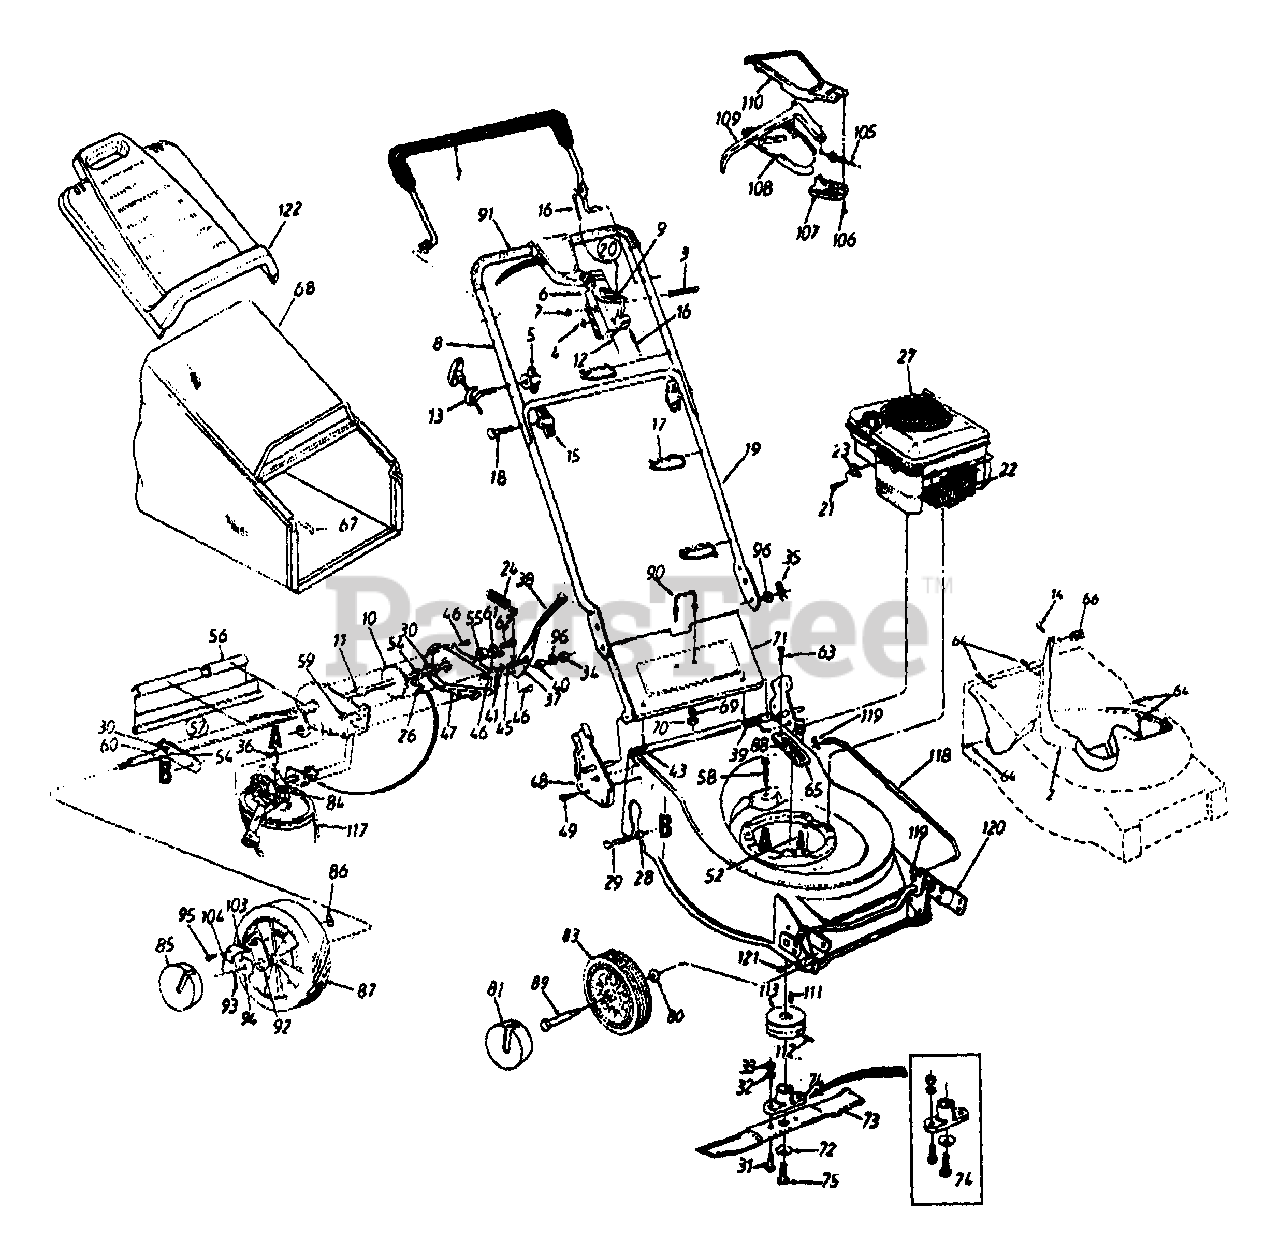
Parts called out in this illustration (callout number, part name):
1	Control Handle Ass'y
2	Rear Baffle
3	Oval C-Sunk Mach. Scr.
4	Spr. Wash. .66" I.D.
5	Wing Nut 1/4-20 Thd.
6	Throttle Body
7	Hex L-Nut 1/4-20 Thd.
9	Throttle Lever
10	Axle Ass'y. 19.12" Lg.
11	Hex Flange Brg. .506" I.D.
12	Throttle Control Wire - 60"
15	Hand Knob
16	Control Cable - 47"
17	Cable Tie
18	Curved Hd. Bolt 5/16-18 x 2" Lg.
20	Throttle Box Comp.
21	Hex Self-Tap Scr. #10-32 x .62" Lg.
22	Spark Plug Boot
23	Casing Clamp
24	Ext. Spring 4.28" Lg.
26	Chain - Endless #48 x 28 Links
27	Engine
28	Shld. Spacer .383" I.D.
29	Hex L-Wash. TT-Tap Scr. 3/8-16 x .75" Lg.
30	Hex Flange Brg. .506" I.D.
31	Hex Bolt 3/8-24 x 1" Lg.
32	L-Wash. 3/8" I.D.
33	Hex Nut 3/8-24 Thd.
34	Hex Patch L-Nut 3/8-24 Thd.
35	Int. Cotter Pin 5/16" Dia.
36	Spacer .325" I.D. x .88" Lg.
37	Spring Lever
39	Torsion Spring - L.H.
40	Shld. Spacer .387" I.D. x .285" Lg.
41	L-Wash. 3/8" I.D.
43	Torsion Spring - R.H.
45	Shld. Pin 3/8-24 x 1.43" Lg.
46	Hex Tap Scr. 1/4 x .38" Lg.
47	Cover Ass'y.
48	Handle Brkt. Ass'y. - R.H.
49	Hex L-Wash. AB-Tap Scr. 1/4 x .62" Lg.
52	Hex L-Wash. Hd. Scr. 3/8-16 x 1" Lg.
55	Spacer .5" I.D. x .88" O.D.
57	Rear Axle Ass'y. Comp.
58	Hex Wash. Hd. Scr. 1/4-20 x 1.5" Lg.
59	Hex Jam Nut 3/8-24 Thd.
60	Spacer .510" I.D. x .875"
61	Bell-Wash. 1/4" I.D.
62	Hex Bolt 1/4-20 x .62" Lg. (Gr. 5)
63	Torx Mach. Scr. 1/4 x .62" Lg.
64	Truss Mach. Scr. #12 x 1" Lg.
65	Height Adj. Plate
66	"U"-Nut #10-16 Thd.
69	L-Wash. 5/16" I.D.
70	Hex Nut 5/16-18 Thd.
74	Blade Adapter Kit
75	Hex Bolt 3/8-24 x 1.5" Lg.
80	Bell-Wash. .38" I.D. x .88" O.D.
83	Wheel Ass'y. Comp.
84	Transaxle Ass'y.
85	Rear Hub Cap
86	Weld Top L-Nut 1/4-20 Thd.
87	Wheel Ass'y. Comp.
88	Height Adj. Seal
90	Chute Door Handle
91	Foam Grip
92	Pawl Plate
94	Ratchet Wheel
95	Shld. Bolt .342" Dia. x .268"
96	Bell-Wash. .38" I.D.
103	Pawl
105	S.P. Cable 52.5" Lg.
106	Flat C-Sunk Hd. Tap Scr. #10 x .75" Lg.
107	Cable Mtg. Cap
108	Control Cover Half - Lower
109	Control Lever
110	Control Cover Half - Upper
111	Sq. Key 3/16" x 3/4" Lg.
112	Set Scr. #10-32 x .25" Lg.
117	"V"-Belt
120	Front Axle Ass'y.
121	Hex B-Tap Scr. 1/4" x .38" Lg.
122	Hardtop Cover
